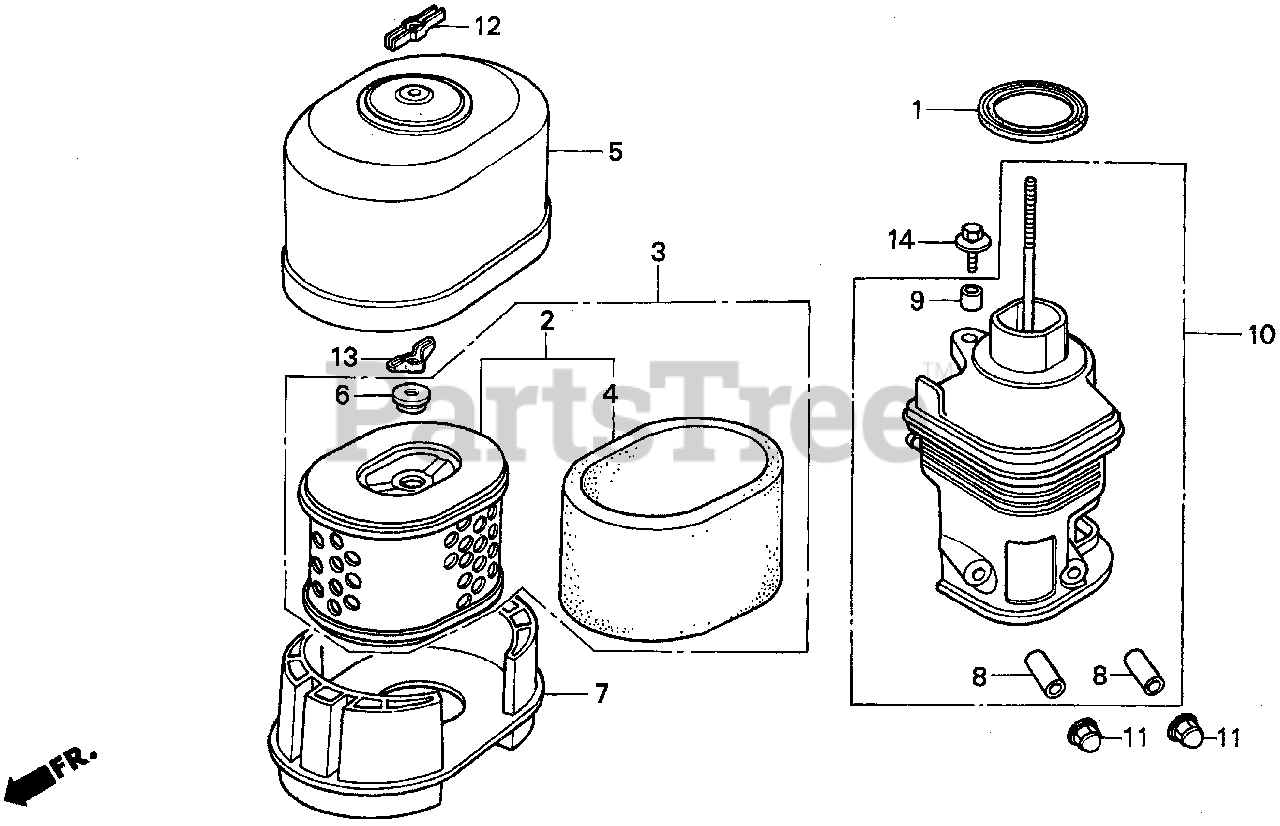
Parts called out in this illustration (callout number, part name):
1	GASKET, ELBOW
2	ELEMENT, AIR CLEANER (DUAL)
3	ELEMENT, AIR CLEANER (DUAL)
4	FILTER (OUTER)
5	COVER, AIR CLEANER (DUAL)
6	GROMMET, AIR CLEANER
7	NOSE, MUFFLER
8	COLLAR, AIR CLEANER
9	COLLAR B, AIR CLEANER
10	ELBOW, AIR CLEANER
11	NUT, CAP (6MM)
12	WINGNUT, AIR CLEANER COVER
13	WINGNUT, TOOL BOX SETTING
14	BOLT-WASHER (6X20)
